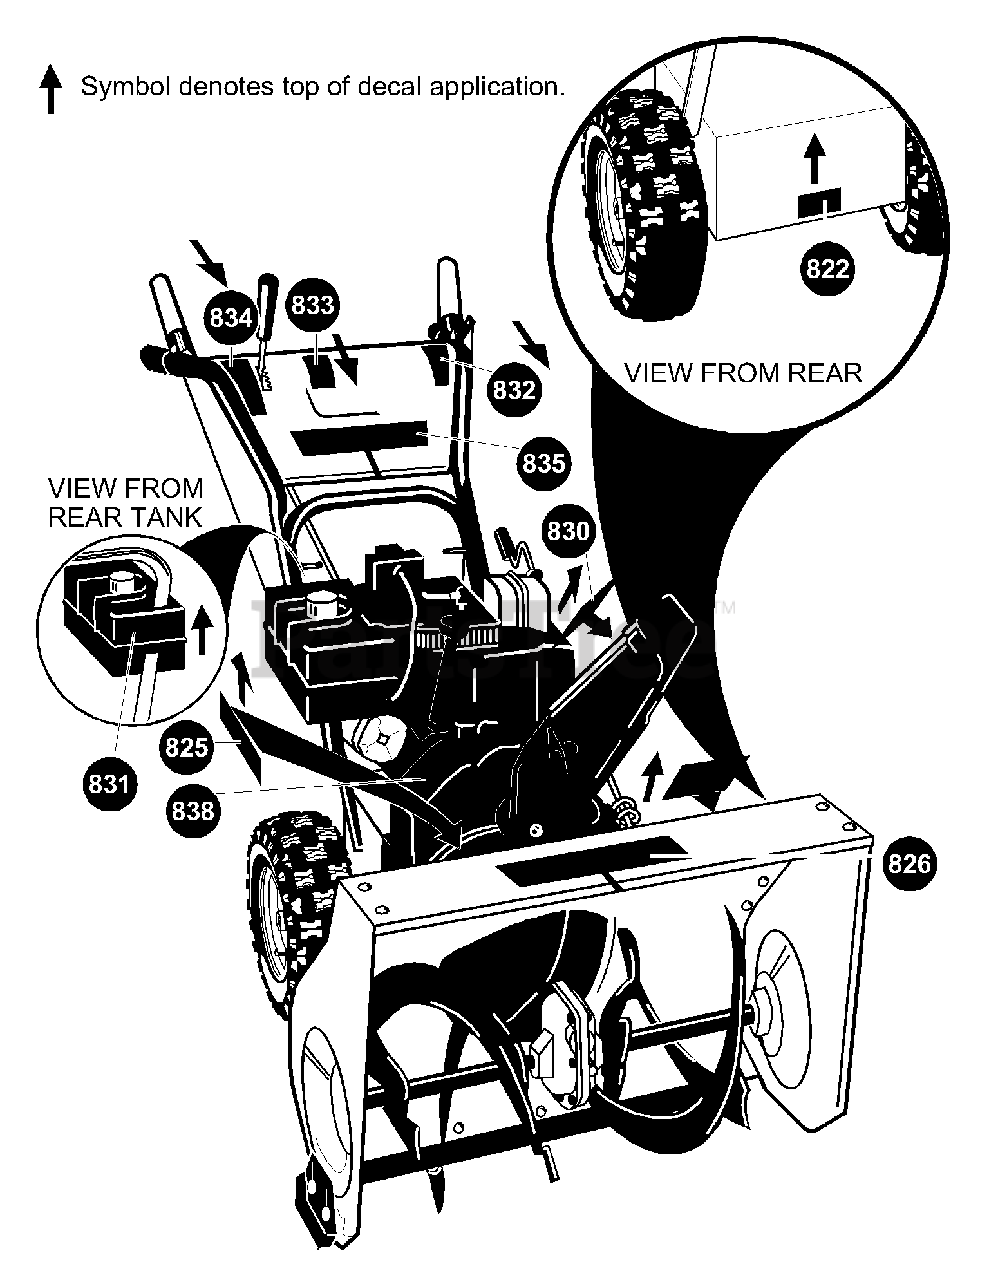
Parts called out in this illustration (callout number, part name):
821	NOT A SERVICABLE PART
822	DECAL, OVER ADJ OF DISC
824	DECAL, DANGER FOOT SYM
825	DECAL, DUAL STAGE
826	DECAL, HUSQ ST7-24
830	DECAL, FINGER FINGER ENG/FR
832	DECAL, TRACT DR-CHUTE ROT.
833	DECAL, SNOW CONDITIONS E/F
834	DECAL, GEAR SELECT/AUG E/F
835	DECAL, CONTROL PANEL
838	DECAL, BELT STRETCH & ADJ
